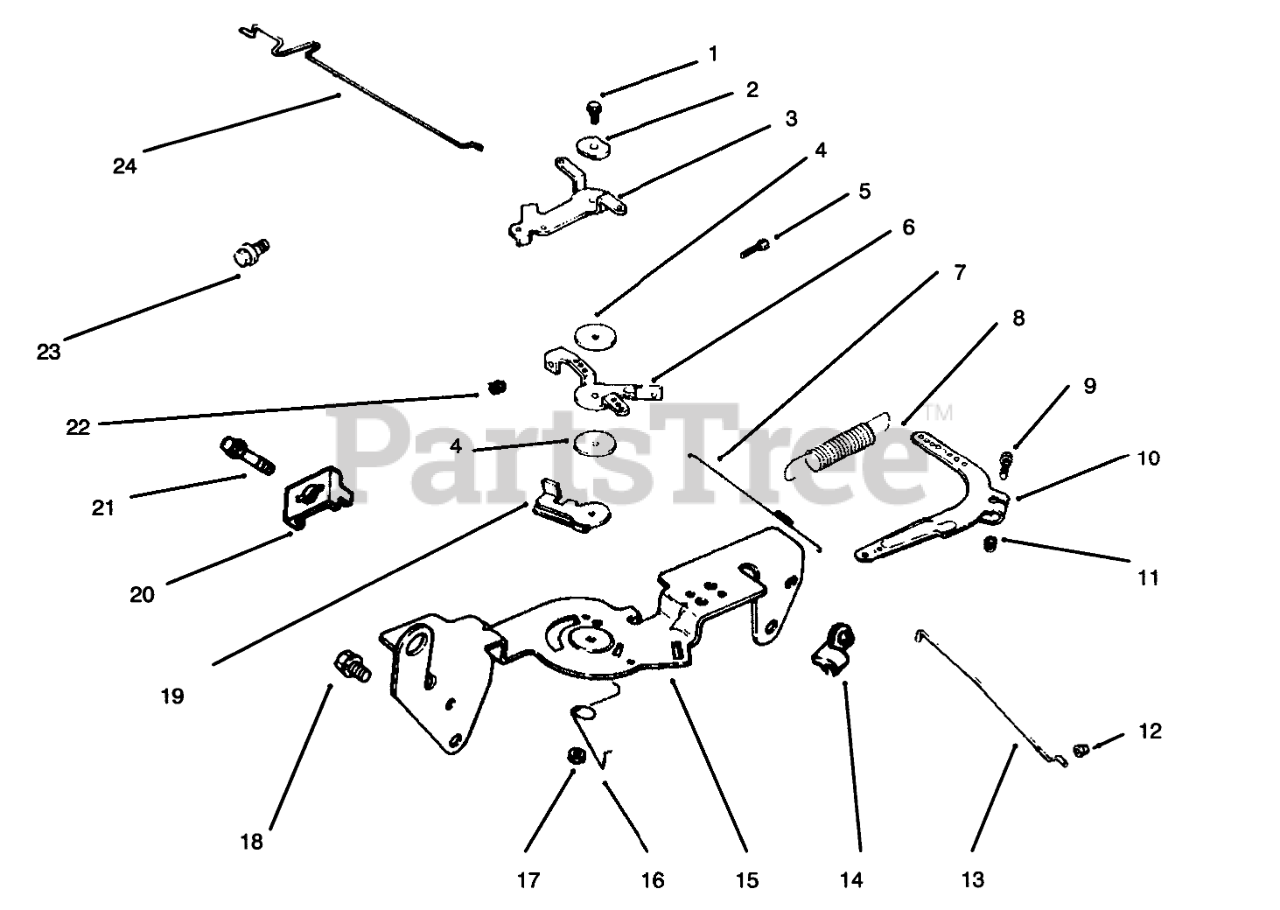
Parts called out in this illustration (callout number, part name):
1	Screw
2	Washer-Wave
3	Lever-Choke
6	Lever-Throttle Control
7	Spring-Linkage
8	Spring-Governor
9	Screw
10	Lever-Governor
12	Bushing
13	Linkage-Throttle
14	Bushing-Linkage
15	Bracket-Control
16	Spring-Choke Return
17	Nut
18	Screw
19	Lever-Throttle Actuator
21	Screw
22	Nut
23	Screw
24	Linkage-Choke
